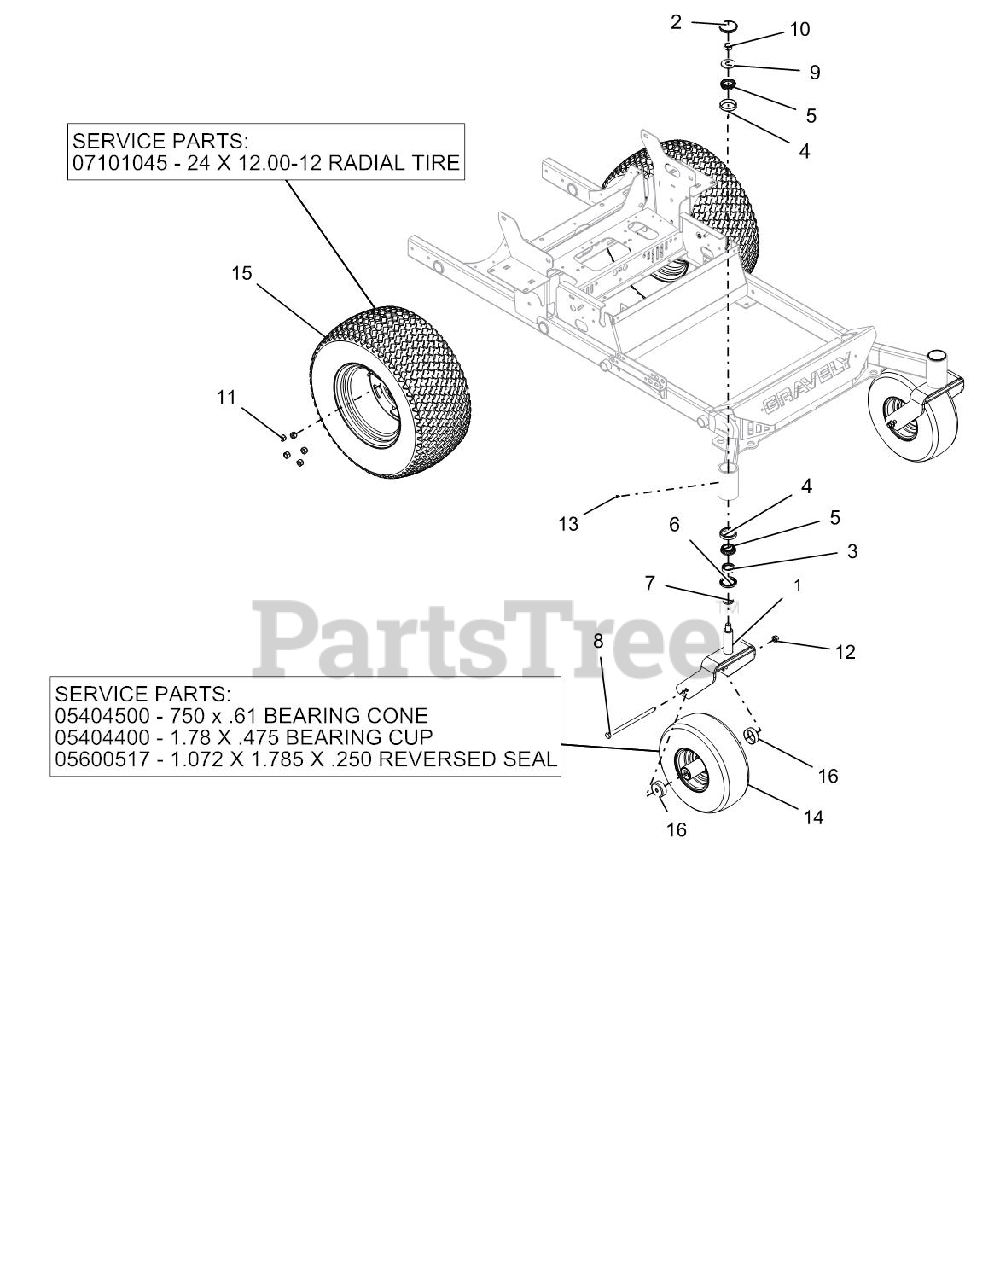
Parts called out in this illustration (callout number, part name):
1	CASTER FORK WMT - RED
2	CAP, DUST
3	SPCR, FRONT CASTER FORK
4	BRG-CUP 2.328X.465
5	BRG-CONE 1.25X.66
6	SEAL, OIL 1.75 X 2.332 X .312
8	BLT-HEX .50-13X9.00 GR5 YWZC
9	WSHR-FL-STL.812X2.00X.148YWZC
10	NUT-JAM TOPLK .75-16 YWZC
11	WHEEL NUT .500-20 YZ
12	NUT-LK-TOP-FLG .50-13 YWZC
13	FTG, .25-28 FLUSH MNT GREASE
14	BRG-CONE .750X.61
14	BRG-CUP 1.781X.475
14	SEAL, 1.125 X 1.781 X .469
14	ASM, WHL/TIRE 15X6.00-6 SEMI
15	TIRE, 24 X 12.00-12 RADIAL
15	ASM,WHL/TIRE 24X12.00-12RADIAL
16	SHIELD, WHEEL BEARING
